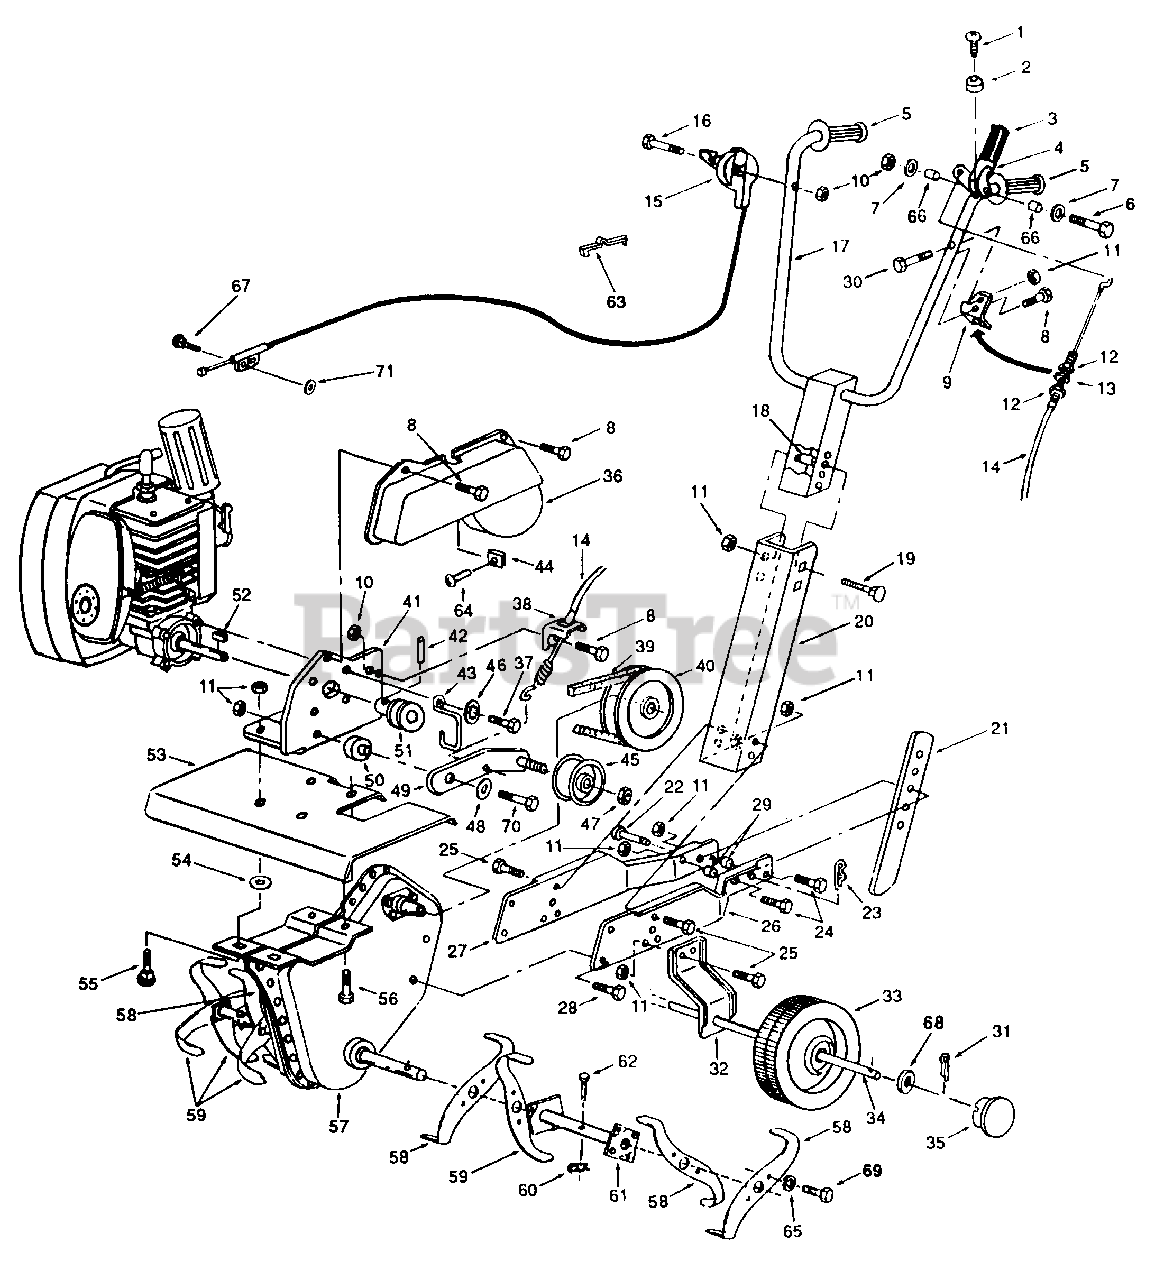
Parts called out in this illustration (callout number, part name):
1	Tap Scr. #10-16 x 1/2
2	Rubber Bumper
3	Vinyl Grip
4	N Clutch Lever Ass'y.
5	Handle Grip
6	Hex Bolt 1/4-20 x 2"
7	Fl-Wash. 1/4" I.D.
8	Hex Tap Scr. 1/4-20 x 1/2
9	Cable Bracket
10	Lock Nut 1/4-20 Thd.
11	Lock Nut 5/16-18 Thd.
12	Hex Jam Nut 5/16-24 Thd.
13	L-Wash. 5/16" I.D.*
14	Clutch Control Cable
15	Throttle Control
16	Hex Bolt 1/4-20 x 1-1/2"
17	Handle Ass'y.
18	Spacer
19	Carr. Bolt 5/16-18 x 2-1/2"
20	Handle Channel Frame
23	Hairpin Cotter
24	Hex Bolt 5/16-18 x 1"
25	Hex Bolt 5/16-18 x 5/8"
26	R.H. Frame Half
27	L.H. Frame Half
28	Hex Tap. Scr. 5/16-18 x 1 /2"
29	N Spacer
30	Hex Bolt 5/16-18 x 1-1/4"
31	Cotter Pin
32	Wheel Bracket
33	Wheel 6"
34	Axle Wheel
35	Hub Cap
36	Belt Cover
37	Hex Bolt 1/4-20 x 5/8"
38	Bracket Clutch Lever
39	V-Belt
40	Pulley Chain Case
41	Plate Engine Mounting
42	Set Screw 5/16-18 x 3/8n
43	Belt Retainer
44	Clip Tinnerman
45	Flat Idler Pulley
46	Int. L-Wash. 1/4" I.D.
47	Hex Jam Thd. L-Nut 3/8-24
48	Fl-Wash. 5/16" I.D.
49	Idler Arm Ass'y.
50	N Pivot Spacer
51	N Engine Pulley
52	N Square Key 1/8 x 3/4"
53	Tine Shield (Red)
54	Spacer
55	Carriage Bolt 5/16-18 x 1 "
56	Hex Bolt 5/16-18 x 3/4"
57	Chain Case Ass'y. Comp.
58	R.H. Tine Blade
59	L.H. Tine Blade
60	Hairpin Cotter
61	Adapter Ass'y. Tine
62	Clevis Pin
63	Cable Tie Plastic
64	Scr. #10-16 x 3/4 Sems
65	L-Wash. 1/4" I.D.
66	Spacer
67	Screw
68	Fl-Wash. 3/8" I.D.
69	Tap Scr. 1/4-20 x 1/2"
70	Hex Bolt 5/16-18 x 1-1/2"
71	N Fl-Wash.
